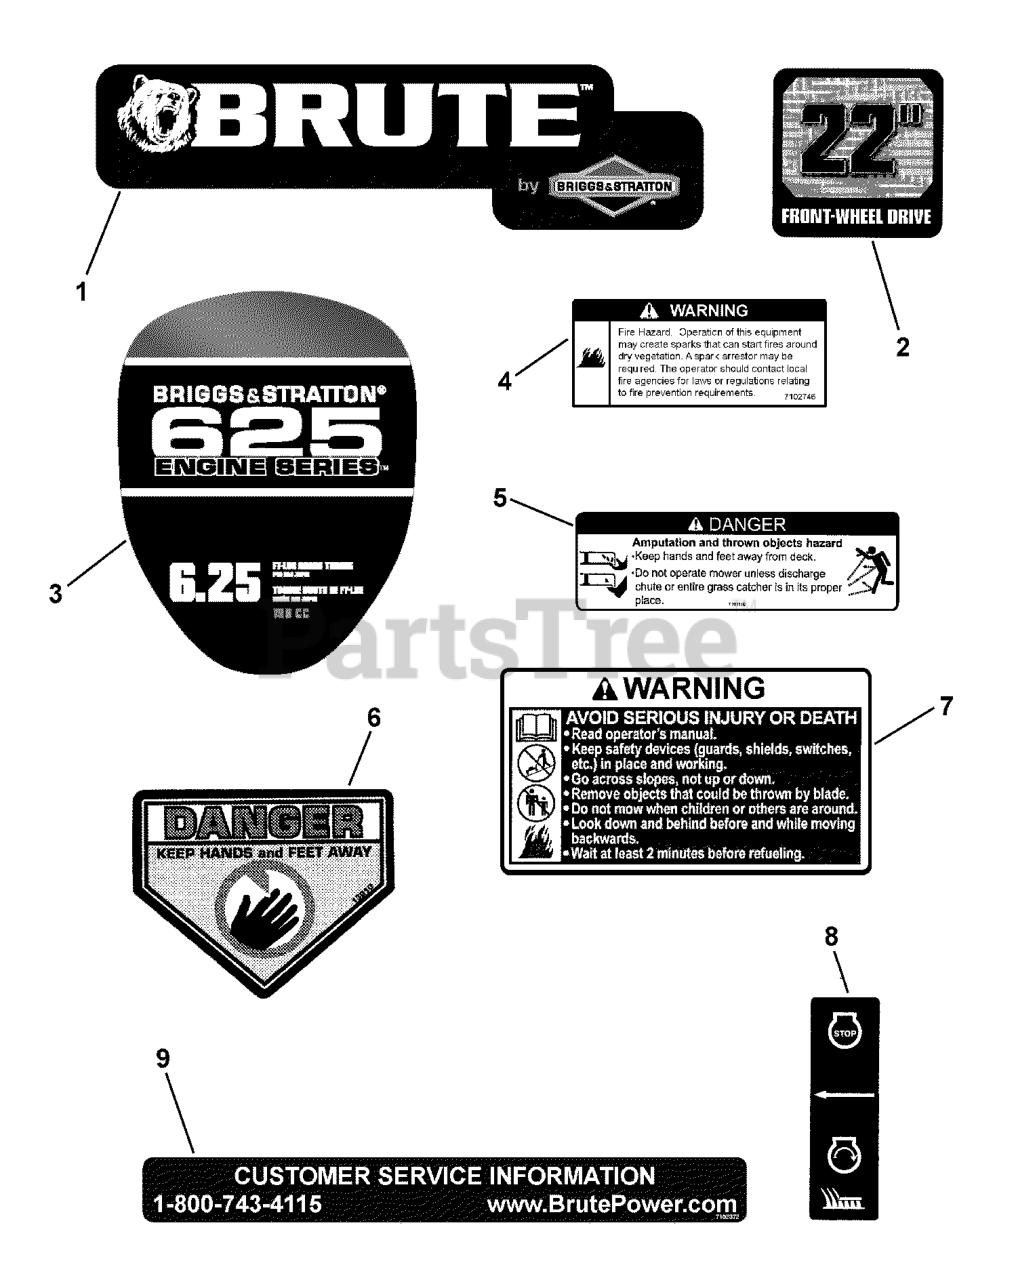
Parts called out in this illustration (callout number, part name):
1	DECAL, Brute Walk-Behind Mower
2	DECAL, 22" Front Wheel Drive Brute
3	DECAL, Engine 625 Series Quantum
4	DECAL, Spark Arrestor
5	DECAL, Danger, Deck, MY 07.5
6	DECAL, Danger, Cut Finger
7	DECAL, Warning, Walk Behind Mower
8	DECAL, OPC Bail International Symbol
9	DECAL, Customer Service, Brute
